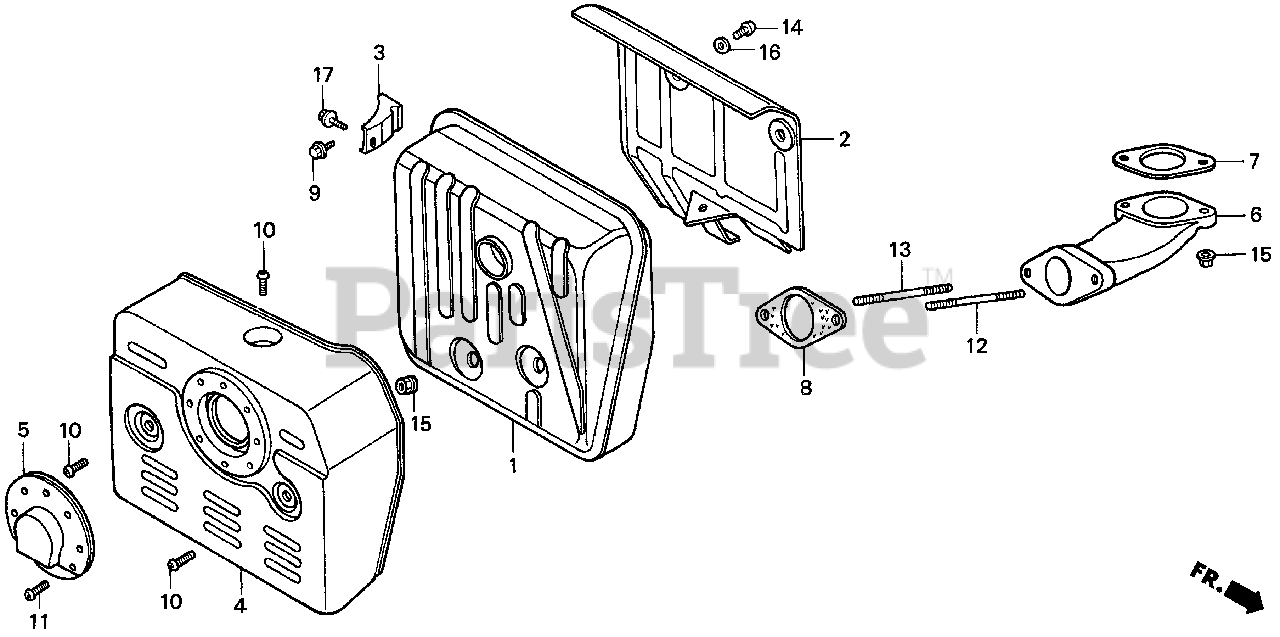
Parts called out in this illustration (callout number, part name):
1	MUFFLER COMP.
2	SEPARATOR, MUFFLER
3	STAY COMP., MUFFLER
4	PROTECTOR, MUFFLER
5	CAP, MUFFLER
6	PIPE, EX.
7	GASKET, EX. PIPE
7	GASKET, EX. PIPE (WACKER)
8	GASKET, EX. PIPE
9	BOLT, FLANGE (8X16)
10	SCREW, TAPPING (5X8)
11	SCREW, TAPPING (4X6)
12	BOLT, STUD (8X60)
13	BOLT, STUD (8X70)
14	SCREW, PAN (6X6)
15	NUT, FLANGE (8MM)
16	WASHER, PLAIN (6MM)
17	BOLT, FLANGE (8X14)
